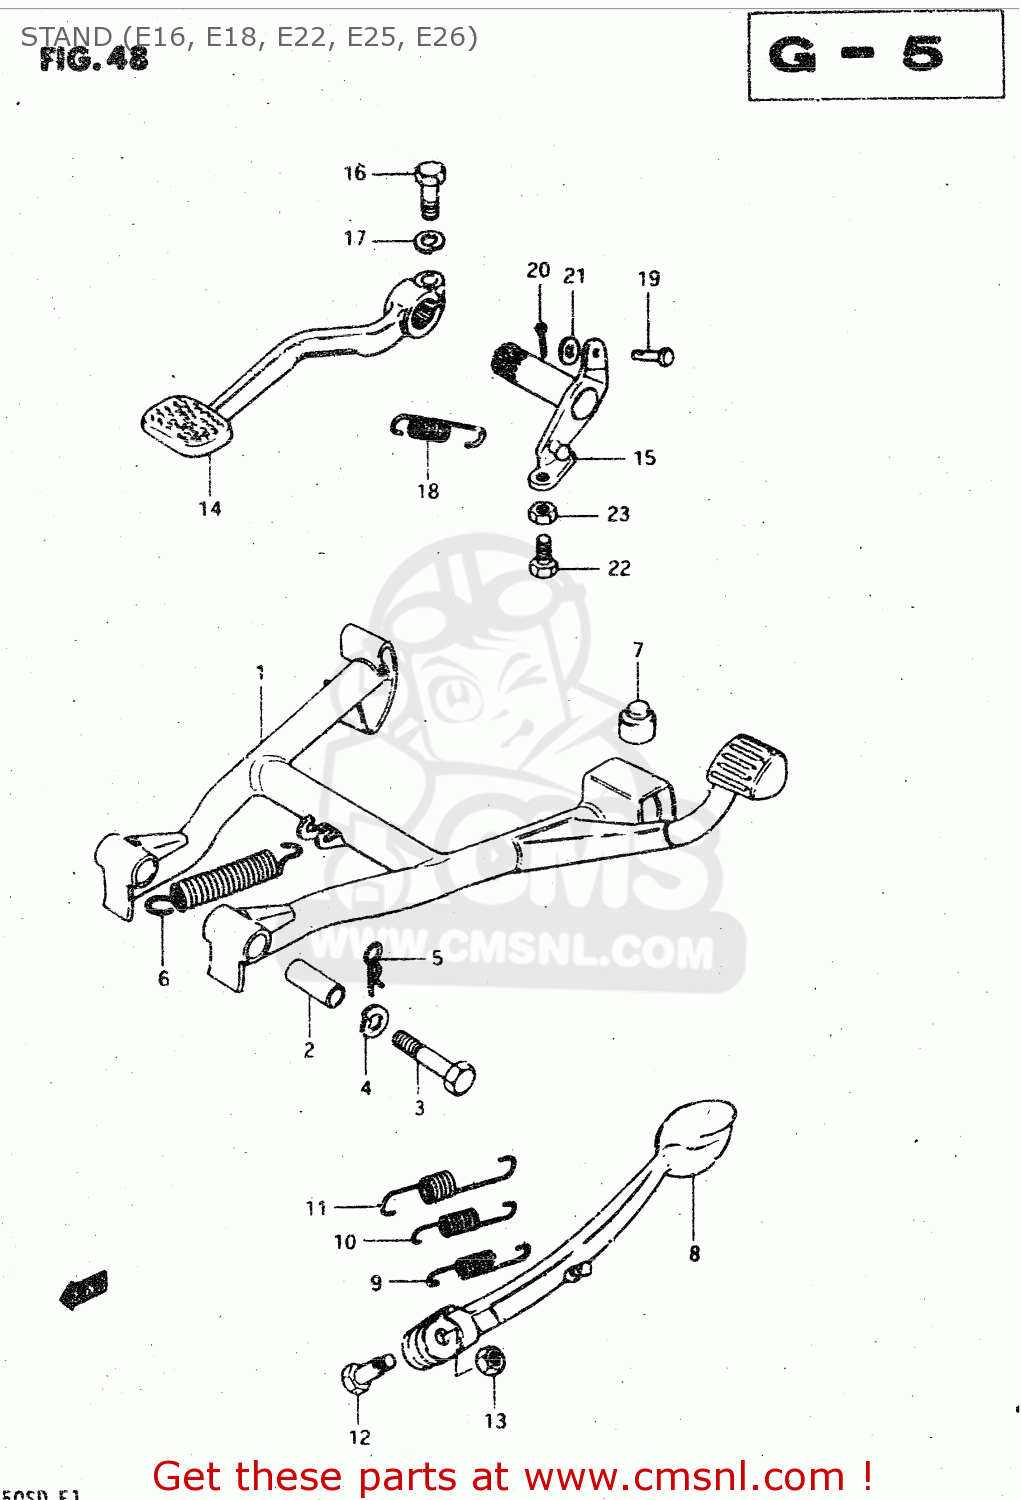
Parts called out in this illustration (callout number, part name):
1	STAND,CENTER
2	SPACER(10X16X38.8)
3	BOLT
4	LOCK WASHER
5	CLIP
6	SPRING
7	CUSHION
8	STAND, PROP
9	SPRING
10	SPRING
11	SPRING
12	BOLT(10X32)
13	NUT
14	PEDAL,BRAKE
15	ARM,BRAKE PEDAL
16	BOLT
17	LOCK WASHER
18	SPRING
19	PIN
20	PIN
21	WASHER
22	BOLT
23	NUT
